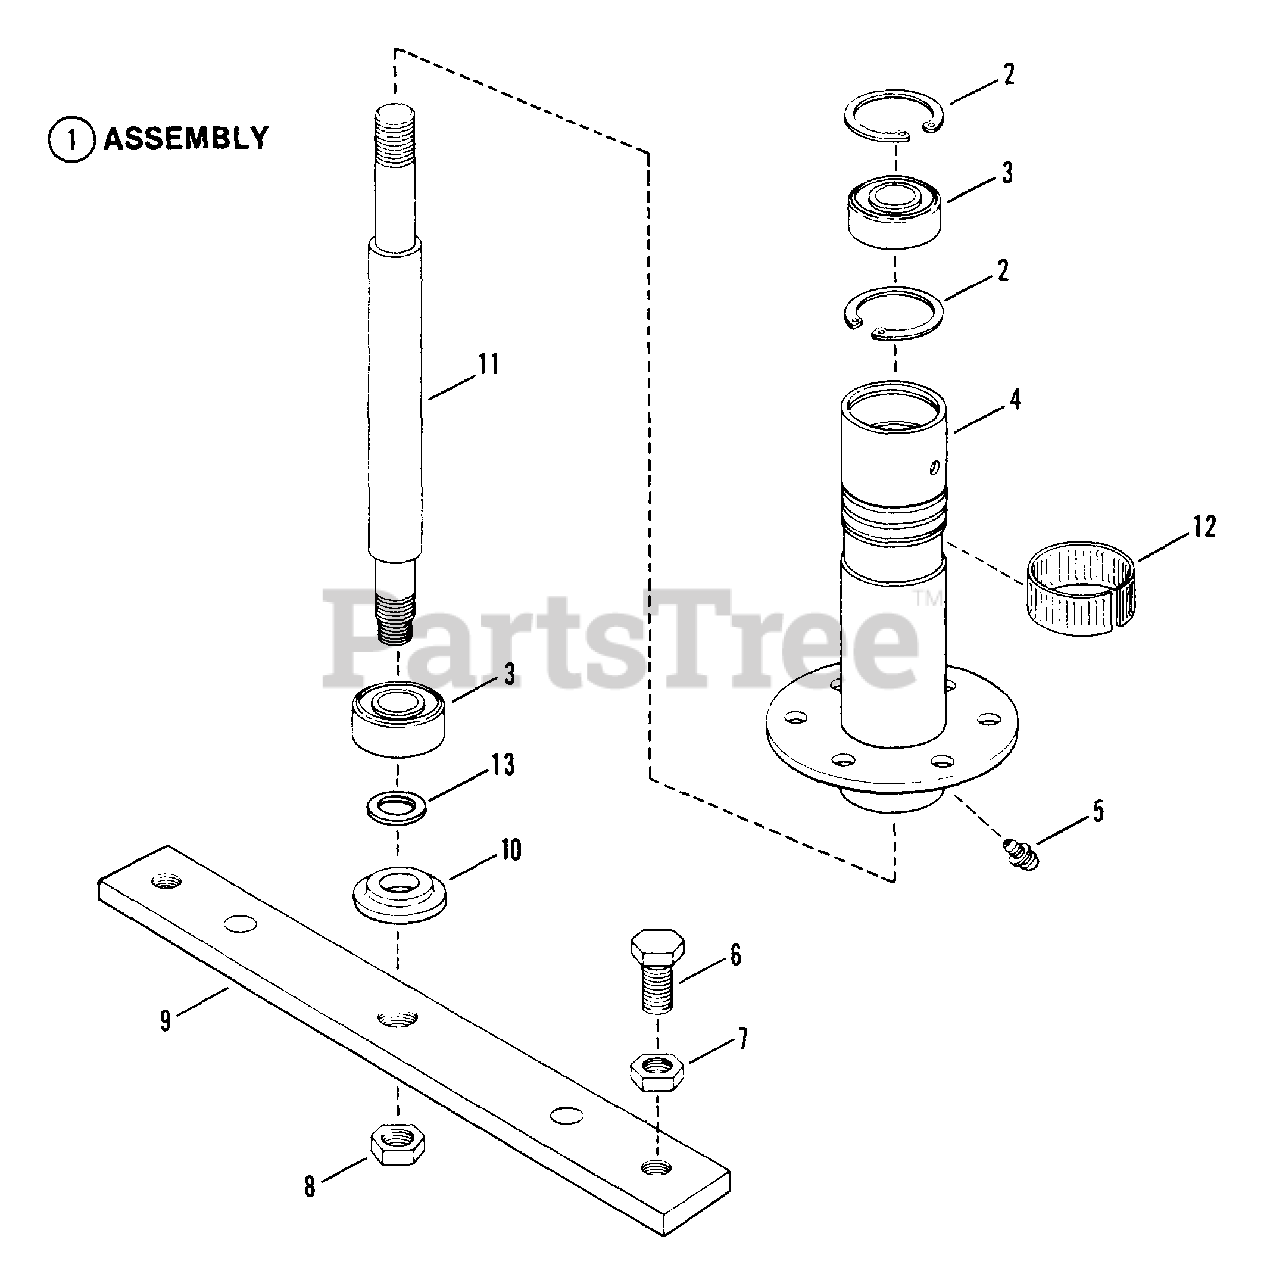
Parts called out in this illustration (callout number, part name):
1	ASSEMBLY, Spindle Housing
2	RING, Retaining
3	BEARING, Spindle
4	HOUSING, Spindle
5	FITTING, Lube (Press fit for .187 hole-no ball)
6	SCREW, 1/2 - 20 x 1" Hex Head Cap, Grade 5
7	NUT, 1/2 - 20 Hex-Jam
8	NUT, 5/8 - 18 Hex Lock
9	HOLDER, Blade
10	WASHER, Spindle
11	SPINDLE, Shaft (10.237" Long)
12	RING, Tolerance
13	WASHER, Shim
